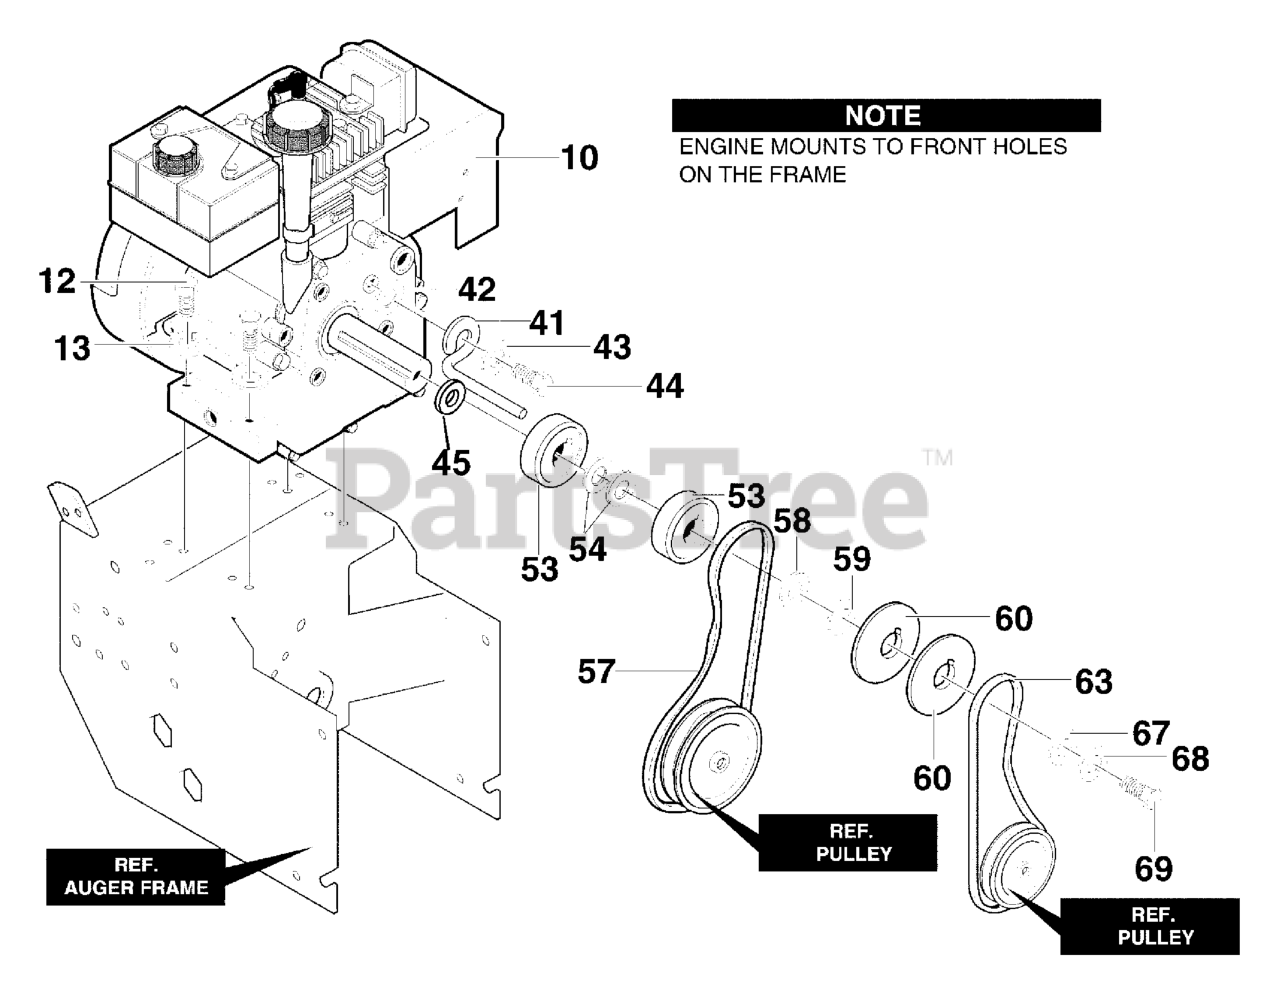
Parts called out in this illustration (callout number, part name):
10	8HP ENGINE
12	SCREW, 5/16-18
13	WASHER, SPTLK .31X.58X.08
41	GUIDE, ROD BELT
42	PLASTIC WASHER
43	WASHER, SPTLK .31X.58X.08
44	SCREW, 5/16-24 x 1.00
53	PULLEY, HALF
54	WASHER, FLAT .752X.91X.02
57	BELT, V 3L 33.13LG
58	FLATWASHER .765X1.12X.06
59	SPACER, SLEEVE
60	PULLEY, ENGINE
63	BELT, V 4L38.1LG
67	WASHER, FLAT .375X1.25X.104
68	WASHER,HVSPTLK .38ID
69	SCREW, 3/8-24 x 1.00
